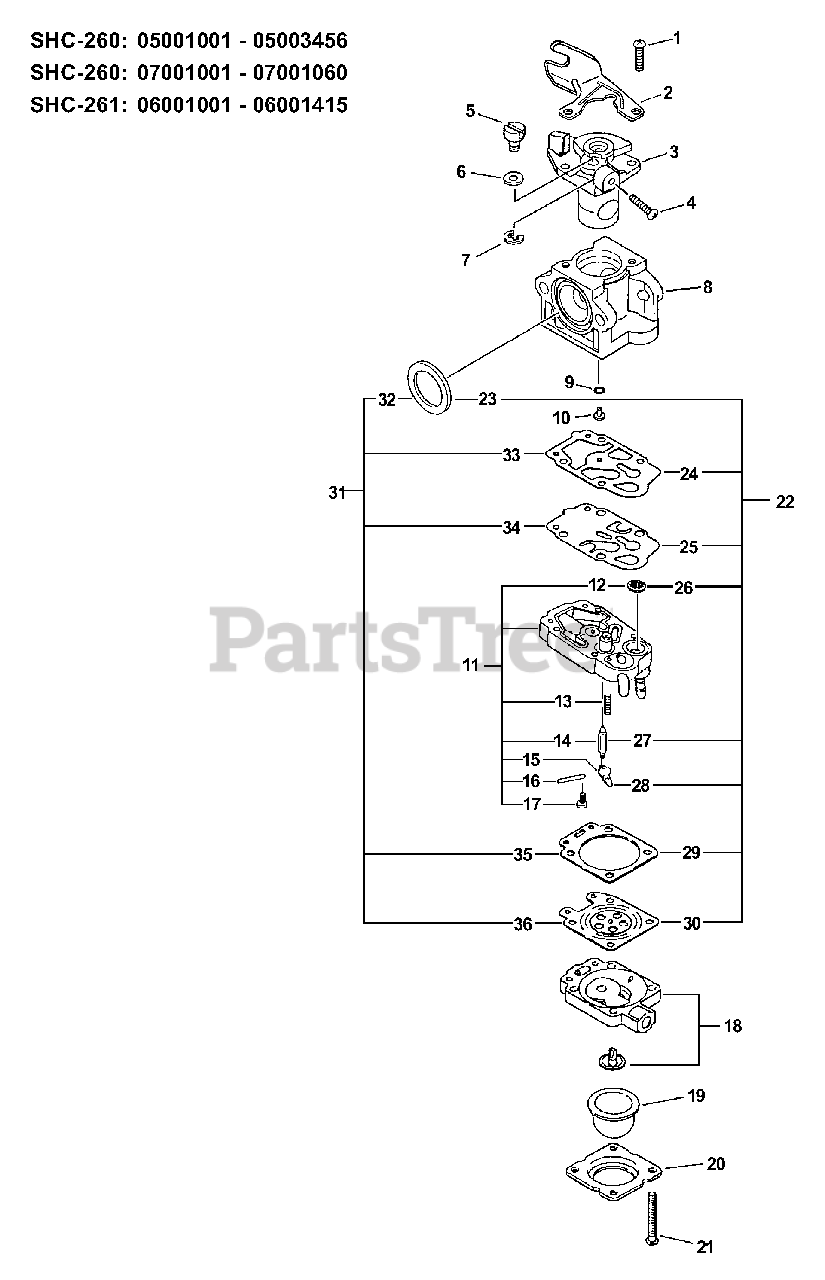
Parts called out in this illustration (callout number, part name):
2	BRACKET, CABLE
3	THROTTLE VALVE ASSY
4	SCREW, IDLE ADJUST
7	RING, RETAINING
8	BODY, CARBURETOR
11	BASE, PURGE
12	STRAINER
13	SPRING, METERING LEVER
14	VALVE, INLET NEEDLE
15	LEVER, METERING
16	PIN, METERING LEVER
17	SCREW, METERING LEVER PIN
18	PURGE BASE ASSY
19	BULB, PURGE
20	RETAINER, PURGE BULB
21	SCREW, PUMP COVER
22	REPAIR KIT
23	SEAL
24	GASKET, PUMP
25	DIAPHRAGM, PUMP
26	STRAINER
27	VALVE, INLET NEEDLE
28	LEVER, METERING
29	GASKET, METERING
30	DIAPHRAGM, METERING
31	DIAPHRAGM/GASKET KIT
32	SEAL
33	GASKET, PUMP
34	DIAPHRAGM, PUMP
35	GASKET, METERING
36	DIAPHRAGM, METERING
